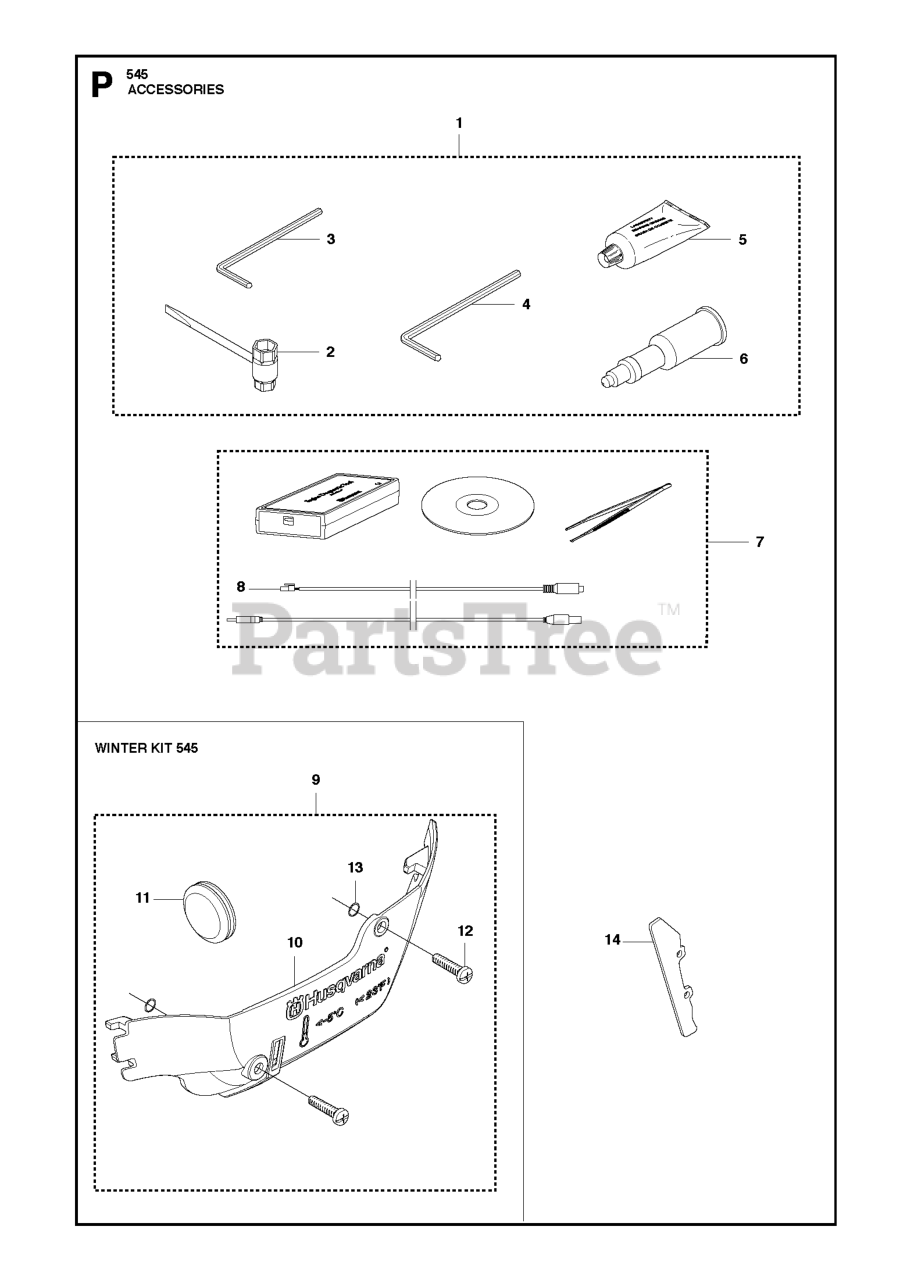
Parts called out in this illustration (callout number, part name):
2	COMBINATION WRENCH
3	L-SPANNER
4	L-SPANNER
5	GREASE
6	Grease Gun
7	SERVICE TOOLS
8	CABLE ASSY
9	WINTER KIT
10	WINTER COVER
11	WINTER PLUG
12	SCREW
13	O-RING
14	BUMPER, BAG
